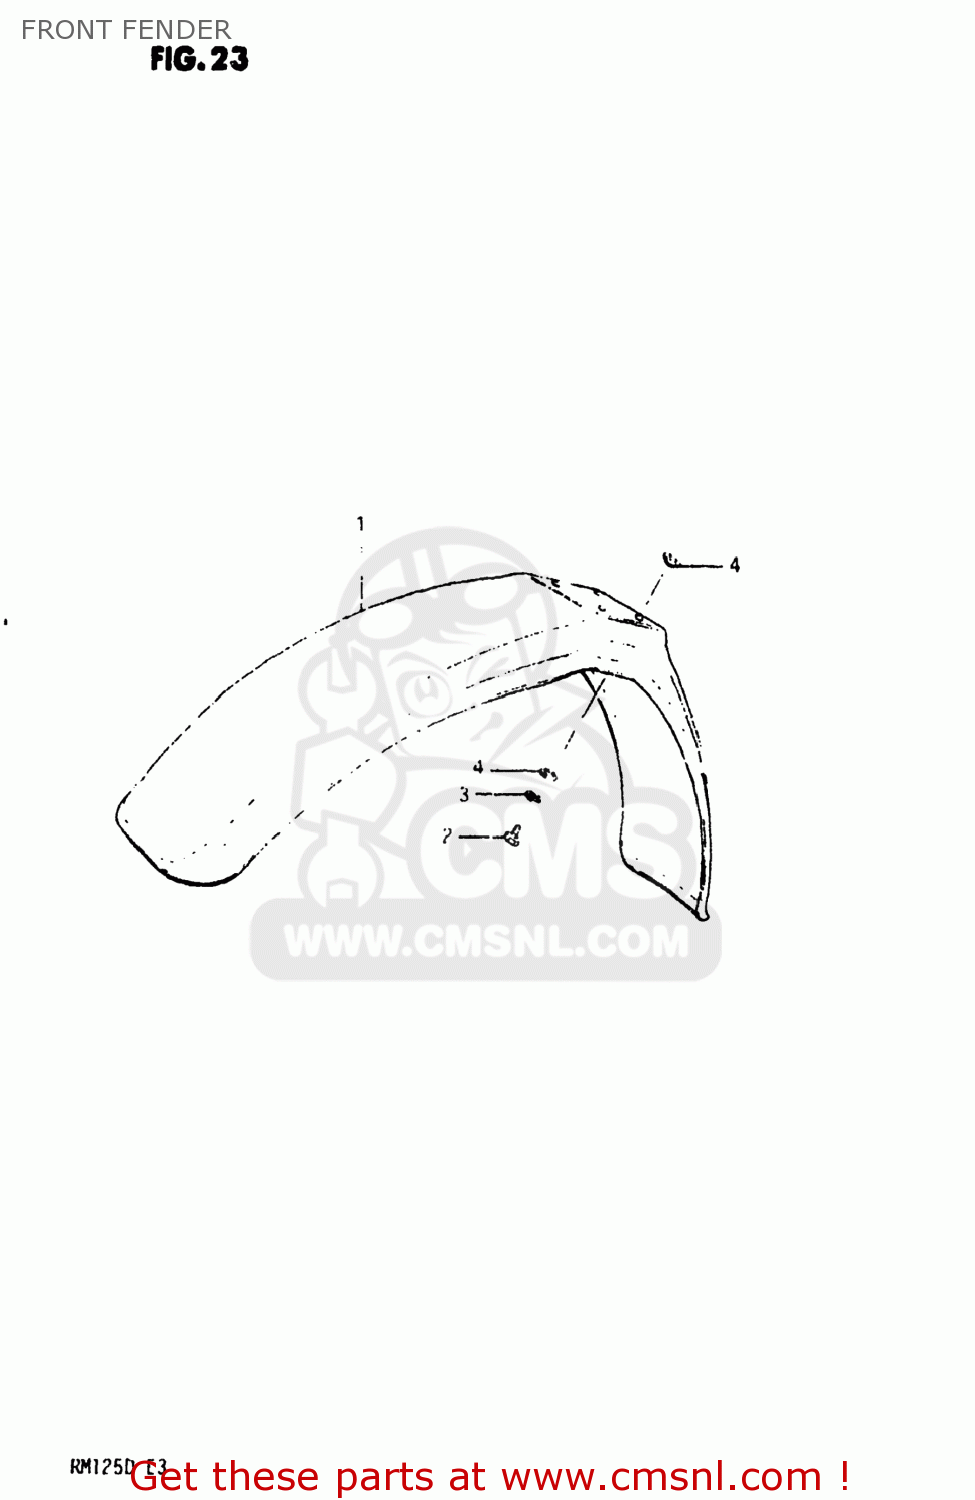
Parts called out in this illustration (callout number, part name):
1	FENDER,FR
2	BOLT, UPPER
3	LOCK WASHER
4	SPACER
